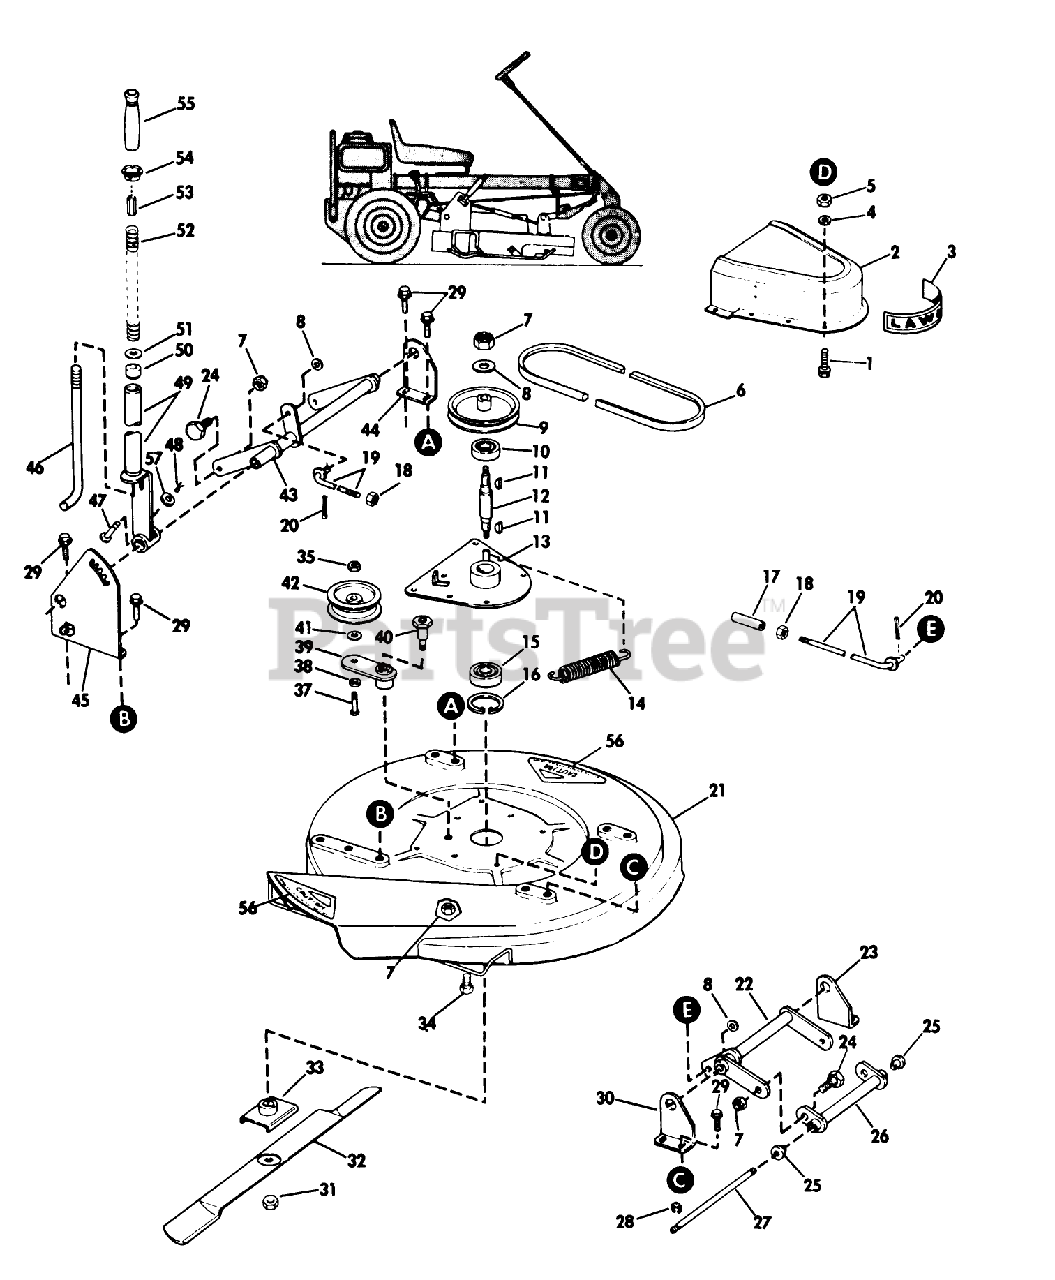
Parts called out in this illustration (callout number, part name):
4	Lockwasher
5	Nut-Belt Cover
18	Jam Nut-Stabilizer Link Assembly
35	LOCKNUT
